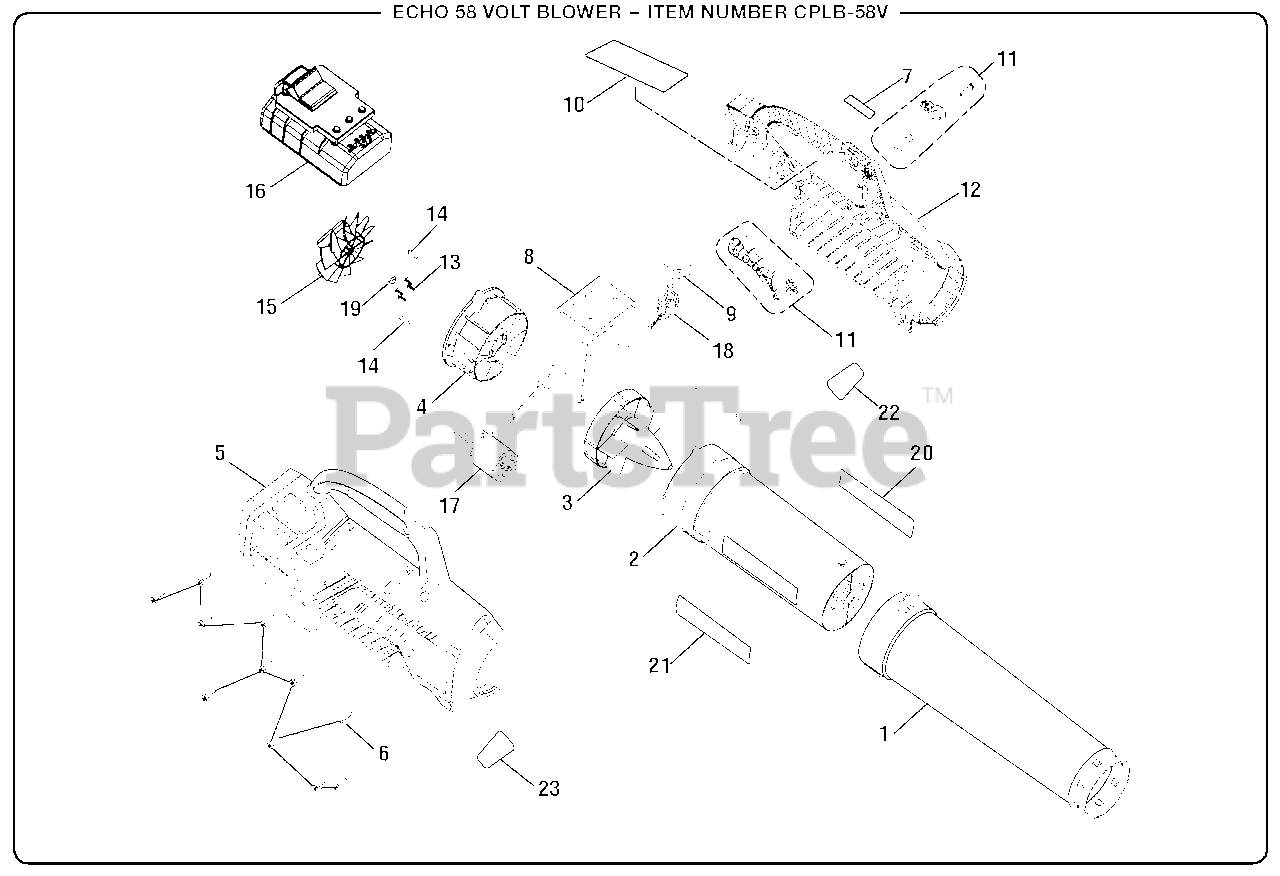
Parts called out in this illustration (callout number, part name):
1	Nozzle & Scraper Assembly
2	Outlet Housing
3	Tailcone
4	Guide Vane Assembly
5	Right Housing Assembly
6	Screw (M5 x 17.5 mm, T20 Torx Pan Hd.)
7	Turbo Boost Label
8	Circuit Board
9	SWITCH PLATE
10	Warning Label
11	Cruise Control Lever Assembly
12	Left Housing Assembly
13	Screw (M3 x 8 mm, Pan Hd.)
14	Screw (M4 x 14 mm, Pan Hd.)
16	Battery Carriage
17	Motor Assembly
18	Variable Speed Switch
19	BUSHING
20	Fan Label (Left)
21	Fan Label (Right)
22	Data Label
23	Data Label
